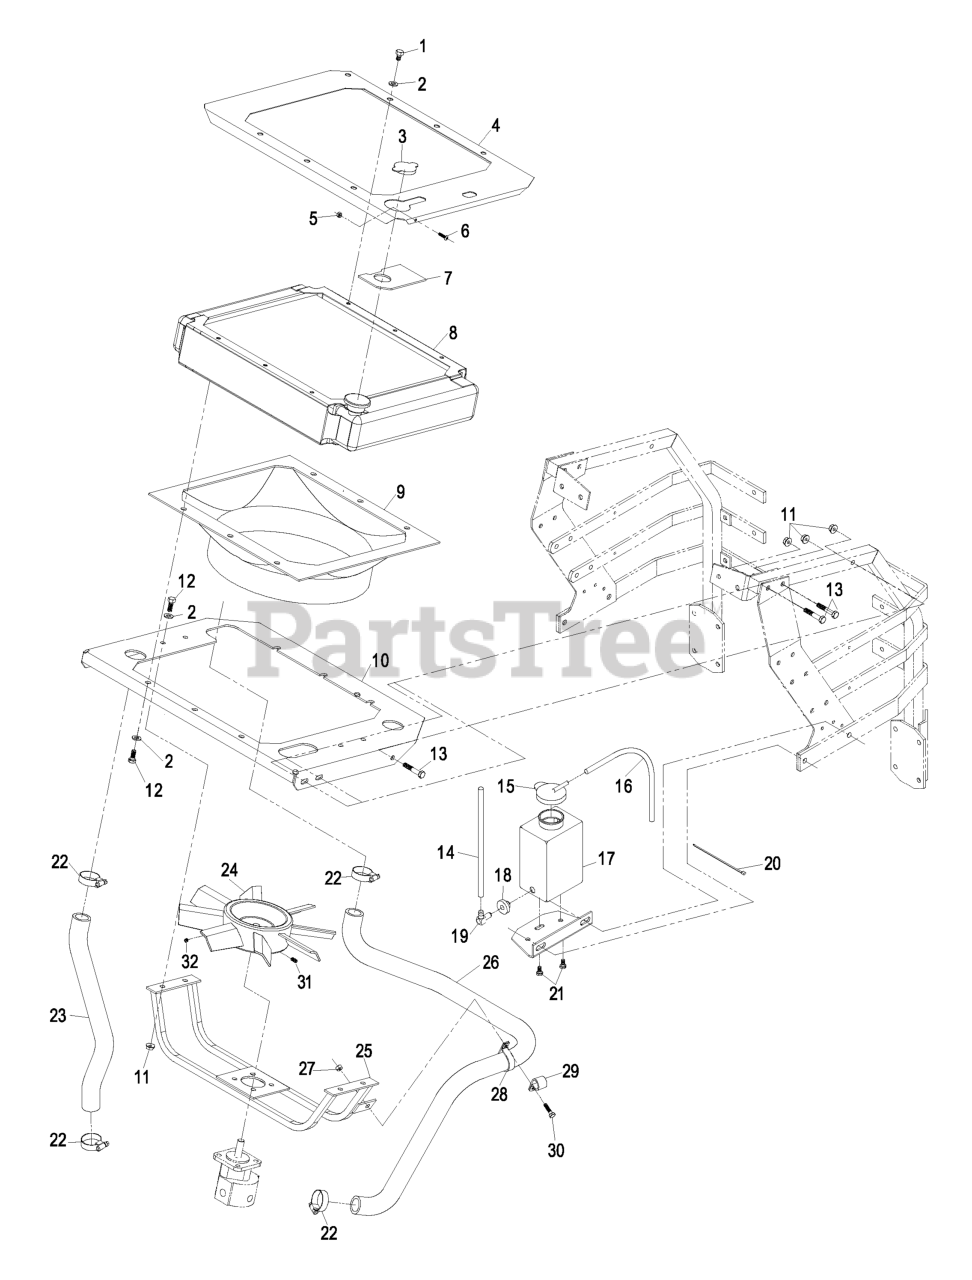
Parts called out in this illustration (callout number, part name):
1	SCREW-HH
2	WASHER-PLAIN
3	CAP-RADIATOR
4	ASM,RAD. TOP PLATE W/DECA
5	NUT-LOCK, NI
6	SCREW-HEAD, TRUSS
7	SHIELD-FILL NECK, RADIATO
9	SHROUD-COOLING, ENGINE
12	SCREW-HH
13	SCREW-HH
15	CAP-TANK, OVERFLOW
17	TANK-OVERFLOW
20	TIE-CABLE
21	SCREW-HH
23	HOSE-OUTLET, ENGINE
25	MOUNT-MOTOR, FAN
26	HOSE-INLET, ENGINE
27	NUT-LOCK, NI
28	CLIP-LOOM
29	CLIP-LOOM
30	SCREW-HH
31	SCREW-SET
32	Setscrew, 1/4-20 X 1/4
